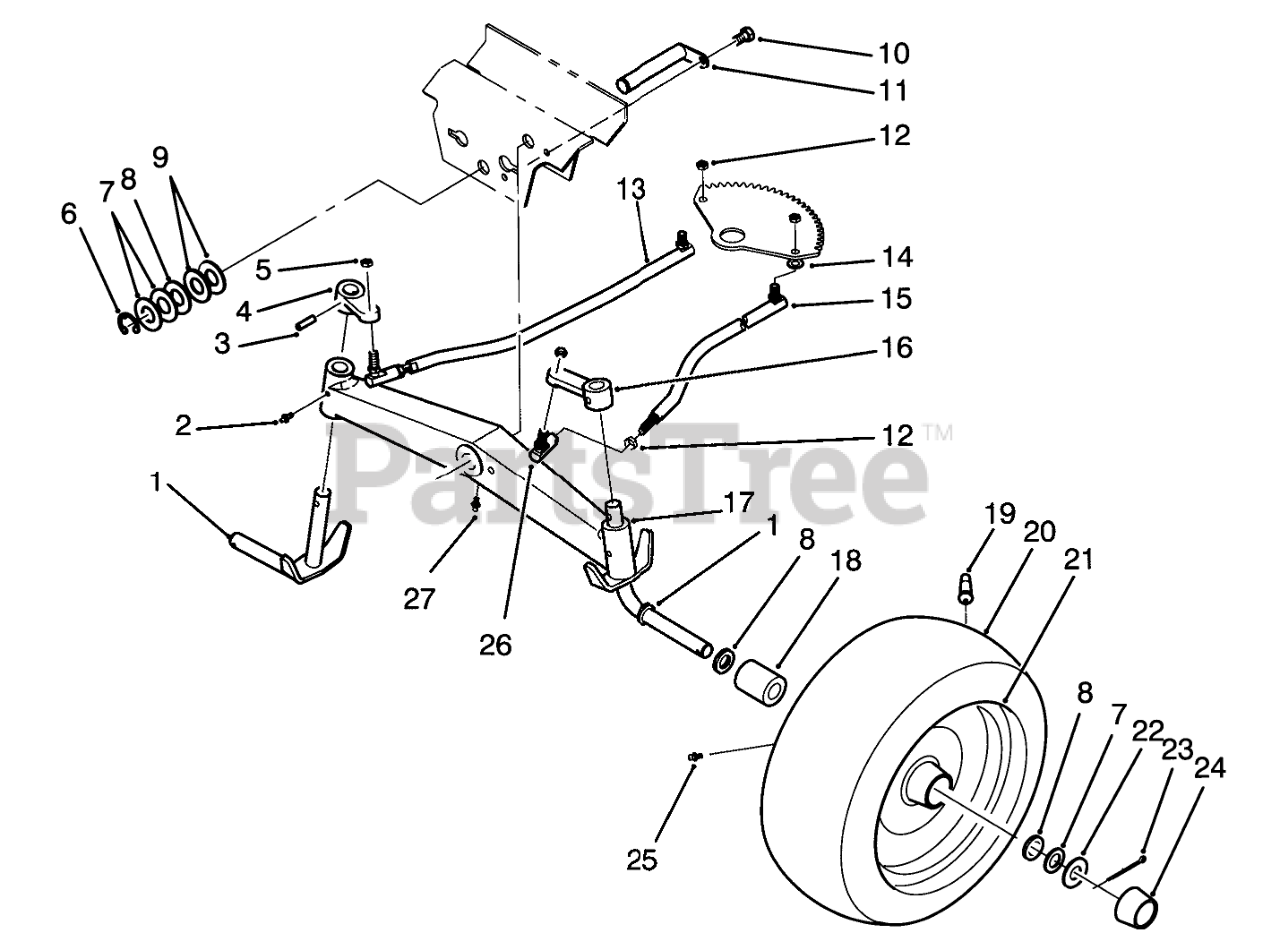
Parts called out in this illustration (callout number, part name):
1	Spindle
2	Fitting-Grease
3	Pin-Roll
4	Arm-Spindle, R.H.
5	Nut
6	E-RING
7	WASHER-SHIM
8	WASHER
9	WASHER
10	Bolt
11	WLDMT-AXLE PIN R
12	NUT-6
13	Ball Link ASM
14	Collar
15	Ball Link ASM
16	Arm-Spindle, L.H.
17	Axle-Front
18	BEARING-WHEEL
19	VALVE
20	Tire (16 x 6.5-8) 2-Ply -2 Wheel Axel
21	Wheel
22	WASHER WHEEL
23	PIN-COTTER
24	HUBCAP
25	ZERK-GREASE
26	BALL-JOINT
27	FITTING-GREASE
